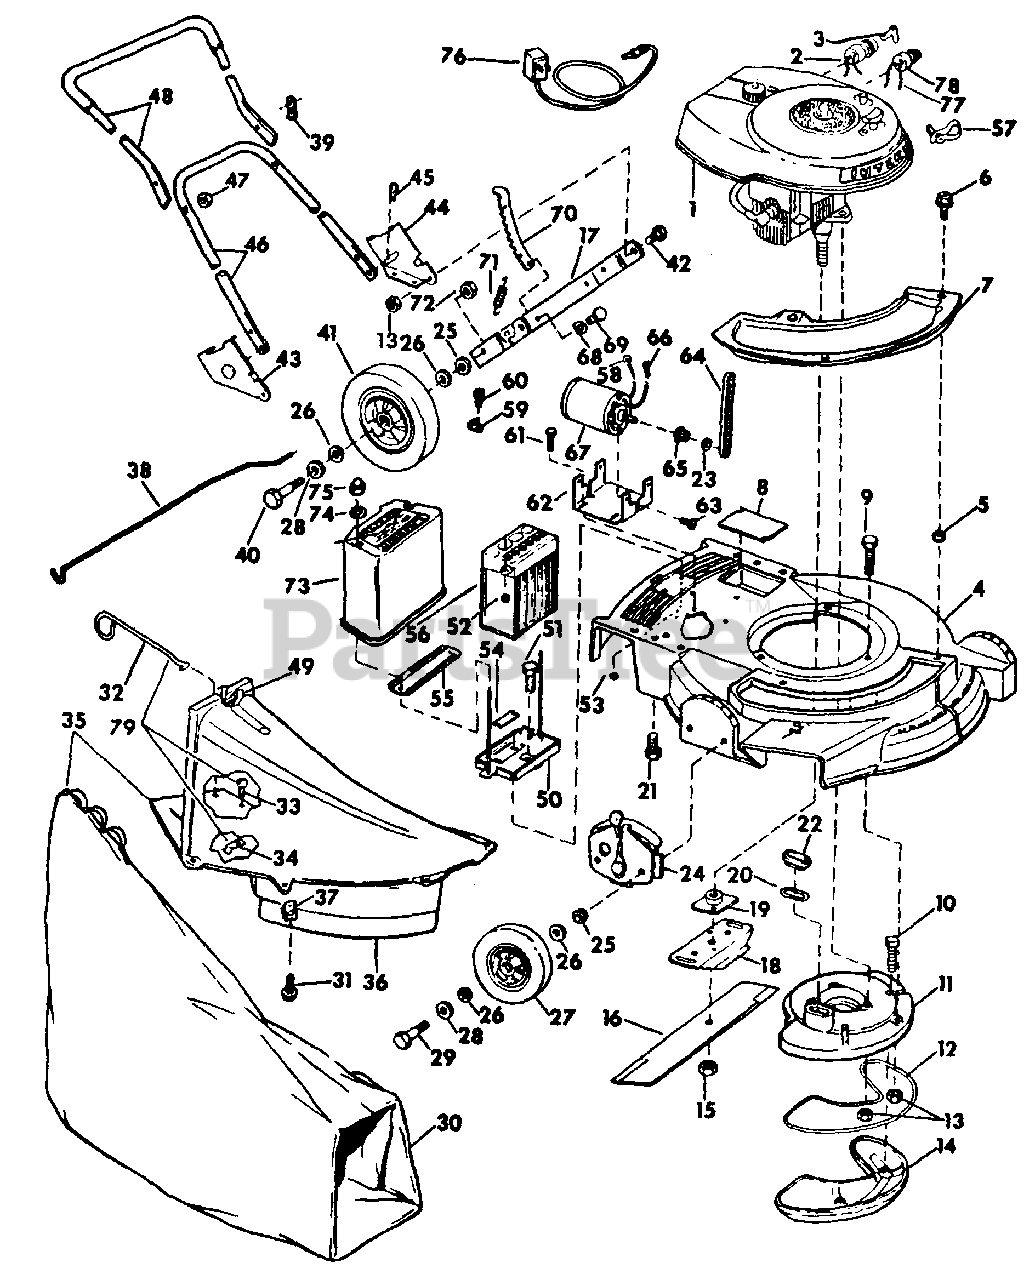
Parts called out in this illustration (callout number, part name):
1	ENGINE, IH
4	HOUSING ASSY, 21 IN
5	NUT, GROMMET
6	SCREW, HEX-HD
7	COVER, CHUTE OPENING
8	COVER, POCKET
9	SCREW, MUFFLER PLATE TO HSG
10	SCREW, MUFFLER TO MUFFLER PLATE
11	PLATE W/SCREW, MUFFLER
12	GASKET, MUFFLER
18	STIFFENER, BLADE
19	COLLAR & PLATE
20	GASKET, EXHAUST
21	SCREW, HANDLE BRACKET
22	SLEEVE, EXHAUST GASKET
24	ADJUSTMENT, HEIGHT
26	WASHER, FELT
27	WHEEL & TIRE, 6 IN.
28	WASHER, WHEEL BOLT HD
29	BOLT, WHEEL FRT SHOULDER
32	GUARD, WHEEL
35	CHUTE ASSY
36	SKIRT ASSY, CHUTE
38	ROD, GRASS BAR
40	BOLT, REAR WHEEL
41	WHEEL & TIRE, 8 IN.
43	BRACKET, HANDLE RH
44	BRACKET, HANDLE LH
46	HANDLE, BOTTOM
47	NUT CENTERLOCK
48	HANDLE & GRIP, TOP
50	BRACKET, BATTERY MTG
51	SCREW, BATTERY BRACKET
52	NUT, CENTERLOCK
53	WASHER, BATTERY MTG BRACKET
54	STRAP, BATTERY MTG BRACKET
55	BRACKET, BATTERY HOLD-DOWN
57	RETAINER, WIRE LEAD TO TANK BRACKET
58	TERMINAL, MOTOR TO BATTERY
59	CLAMP, PIPE
61	SCREW, MOTOR & SWITCH MTG
62	BRACKET, MOTOR MTG
63	SCREW, THD CUTTING
64	BELT, STARTER MOTOR
66	TERMINAL, MOTOR TO SWITCH
67	MOTOR, ELECTRIC
68	WASHER, SPRING
73	COVER W/PRODUCT GRAPHIC, BATTERY
74	WASHER, BATTERY COVER
75	NUT, BATTERY COVER
76	CHARGER, TRICKLE
77	JACK LEAD & TERMINAL ASSY
79	GUARD ASSY, WHEEL
